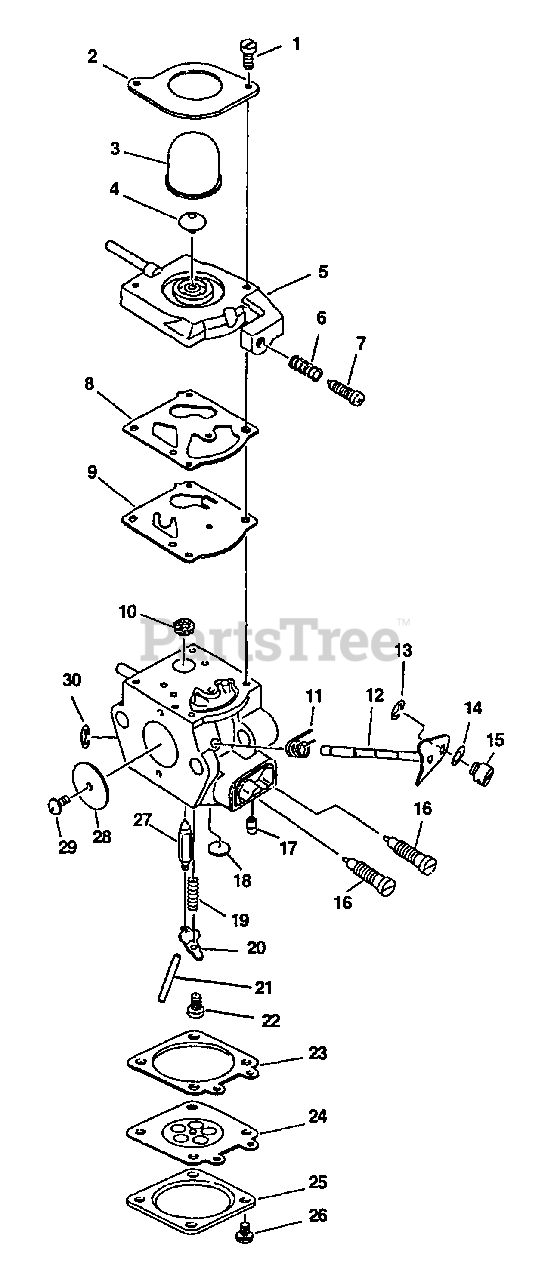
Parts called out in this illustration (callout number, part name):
1	SCREW, PUMP COVER
2	RETAINER, PURGE BULB
3	BULB, PURGE
4	VALVE, CHECK
5	BASE, PURGE
6	SPRING, IDLE ADJUST
7	SCREW, IDLE ADJUST
8	GASKET, PURGE
9	DIAPHRAGM, PURGE
10	STRAINER
11	SPRING, THROTTLE RETURN
12	SHAFT, THROTTLE
13	RING, RETAINING
16	NEEDLE - MIXTURE
17	NOZZLE, CHECK VALVE
18	PLUG, WELCH
19	SPRING, METERING LEVER
20	LEVER, METERING
21	PIN, METERING LEVER
22	SCREW, METERING LEVER PIN
23	GASKET, METERING
24	DIAPHRAGM, METERING
25	COVER, METERING
26	SCREW
27	VALVE, INLET NEEDLE
28	VALVE, THROTTLE
30	RING, RETAINING
